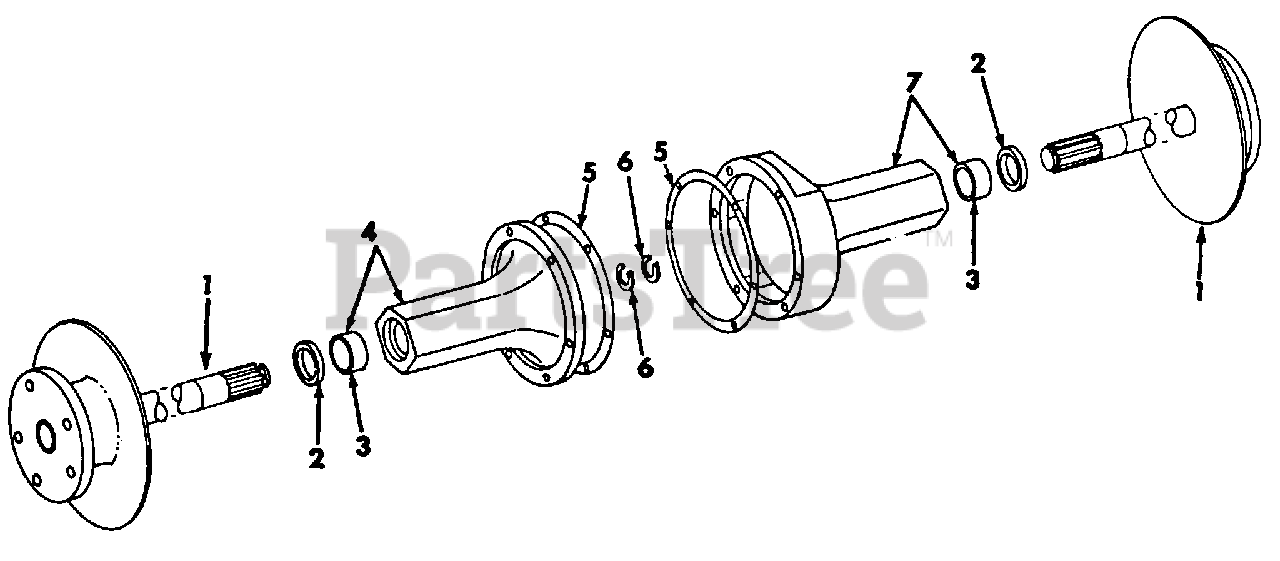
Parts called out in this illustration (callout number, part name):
1	Axle Assy, Rear
2	Seal, Rear Axle Oil
3	Bearing, Rear Axle Carrier Needle
4	Carrier Assy, Rear Axle LH
5	Gasket, Rear Axle Carrier
6	Ring, Rear Axle Retaining Snap
7	Carrier Assy, Rear Axle RH
